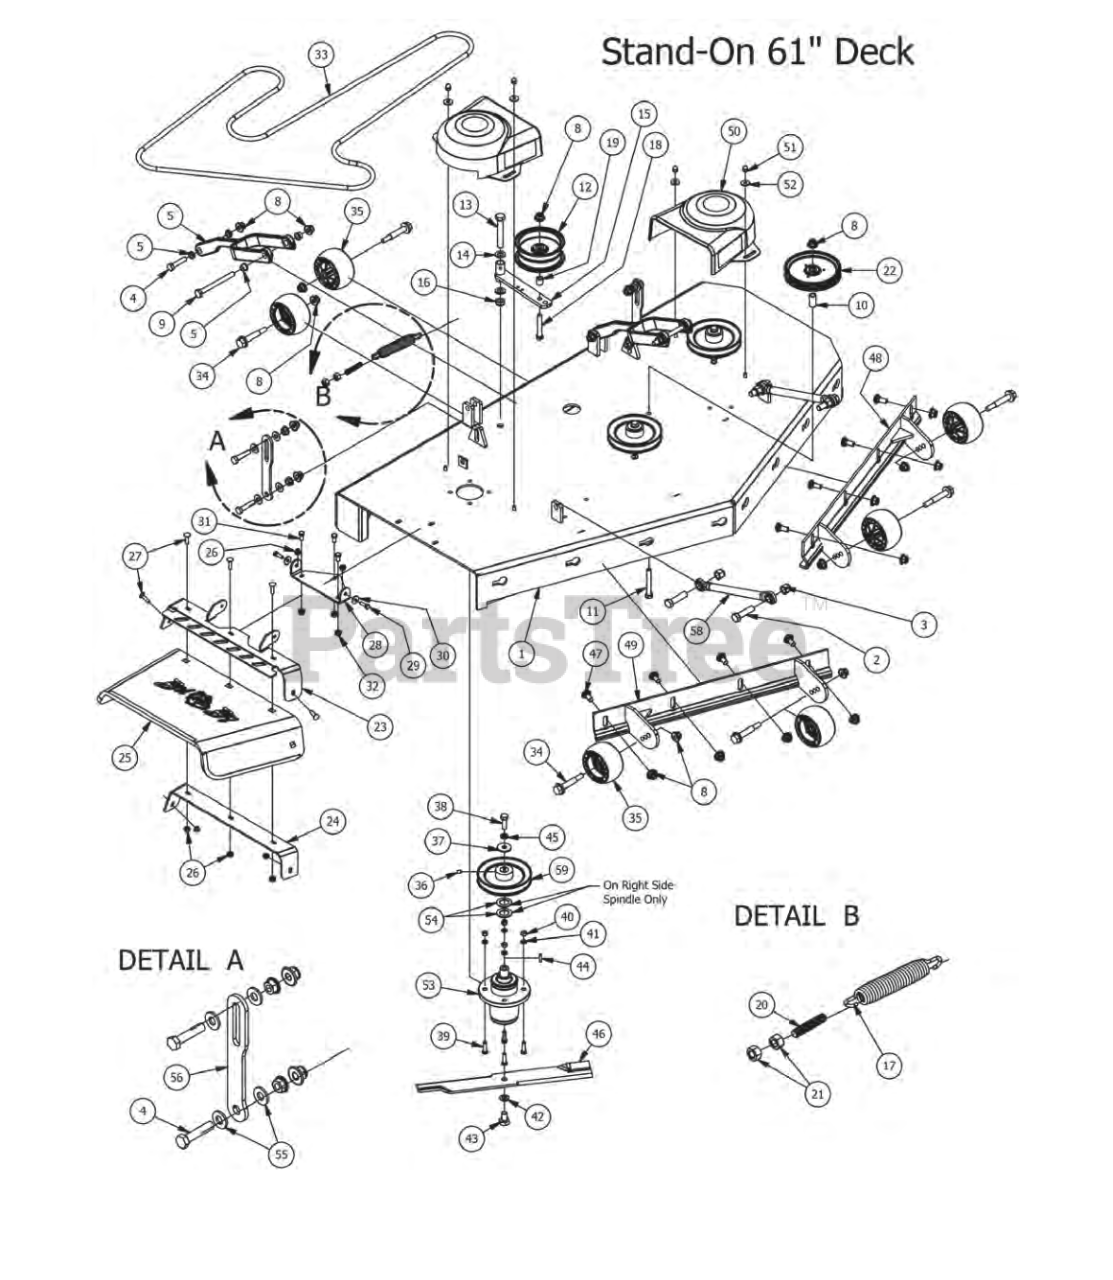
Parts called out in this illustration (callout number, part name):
1	61" 2015 Stand-On Deck (Welded Assembly)
2	5/8" x 2 1/2" Hex Bolt
3	5/8 Std NC Nylock Nut
4	1/2-13X 2-1/4 GR Hex Bolts
5	Deck Arm Assembly
8	1/2-13 Nylon Flange Nut-Orange
9	1/2" x 5 1/2" Bolt
10	.502 ID X.75 OD X 1.500 Leng
11	1/2 x 3 1/2 Flange Bolt Grade 8
12	5 3/4" Deck Idler Pulley
13	5/8" x 4" Hex Bolt
14	635 ID Plastic Washer
15	Deck Idler 2009 AOS
16	5/8" Nylock (1/2 Jam)
17	2009 Deck/Pump Idler Spring
18	1/2-13 x GR 5 Hex Bolt Zinc
19	3/4 OD x 1/2 ID x 3/4 Length
20	All Thread-pump Idler Tensioner
21	1/2" Hex Nut
22	5-3/4 Idler Pulley
23	Upper Hanger
24	Discharge Lower Chute Bracket
25	Rubber Discharge Chute
26	5/16" Nylon Flange Nut
27	5/16" x 1 1/4" Carriage Bolt
28	Discharge Chute Hanger (deck mounted)
29	5/16" x 1" Bolt
30	360 ID Plastic Washer
31	3/8" x 3/4" Hex Bolt
32	3/8" Flange Nut
33	54" MZ Magnum Belt - B138.
34	Deck Wheel Bolt
35	Anti-Scalp Rollers
36	5/16 Set Screw
37	1/2 Belleville Washer
38	1/2"-20 x 1 1/2 - Grade 5 Fine Thread Bolt
39	3/8" x 1 1/4" Hex Bolt
40	3/8-16 Hex Nuts Zinc
41	3/8" Lock Washer
42	5/8" Lock Washer
43	5/8" x 1 1/2" Gr8 Hex Bolt (Fine)
44	1/4" x 1" Key
45	1/2" Lock Washer
46	Fusion Blade
47	1/2" x 1 1/4 Carriage Bolt
48	61 Deck Adustable Front (Left)
49	61 Deck Adustable Front (Right)
50	Pulley Cover
51	Acorn nut-pulley Cover
52	360 ID Plastic Washer-Black
53	OUTLAW SPINDLE ASSEMBLY
54	1 1/8" Flat Spacer
55	505 Nylon Spacer
56	Longer deck hanger
57	1/2" Flange Nut
58	Turnbuckle (Top Link)
59	6 1/4" Drive Pulley
